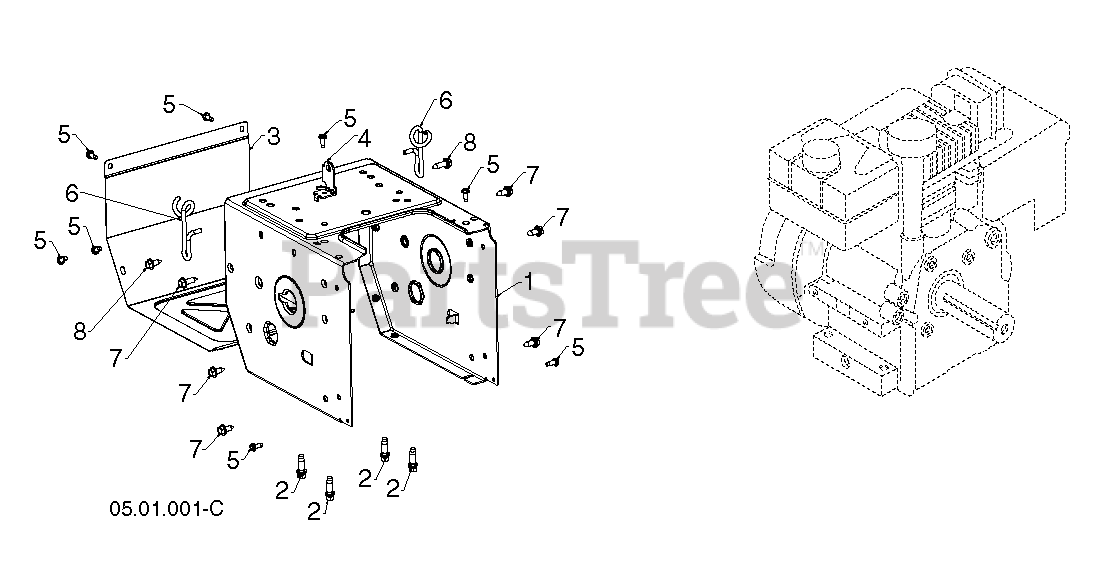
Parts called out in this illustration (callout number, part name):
1	FRAME.GEAR.CASE.SNOW.BLACK
2	BOLT 3/8-16X1-1/8
3	Snow Frame Cover, Black
4	BRACKET.SHIFTER.BZP
5	SCREW 14-20 X 5/8
6	RP.SUPPORT CABLES WIREFORM
7	BOLT.HEX.HD.WASHER.5/16-18X.75
8	Hex Washer Head Bolt, 5/16-18 X 3/4 Thread Forming
